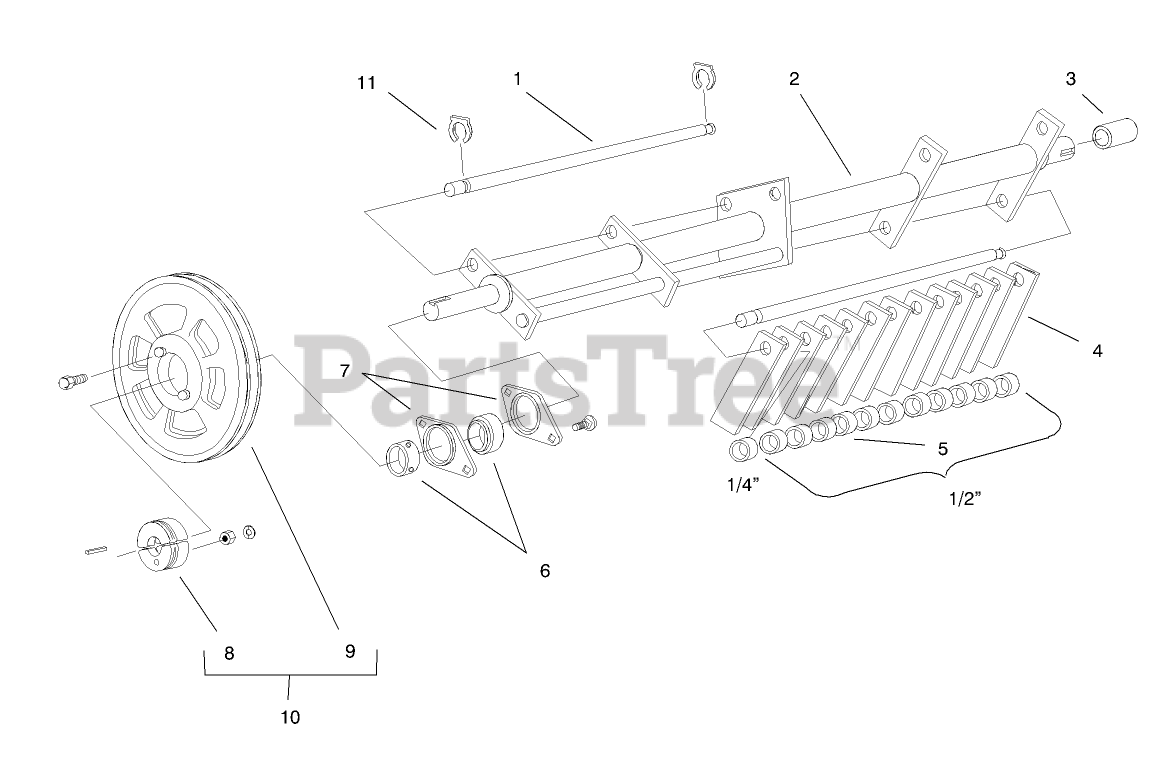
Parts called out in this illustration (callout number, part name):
5	SPACER-SET OF 48=1
9	V-PULLEY
10	V-PULLEY
11	C CLIP
